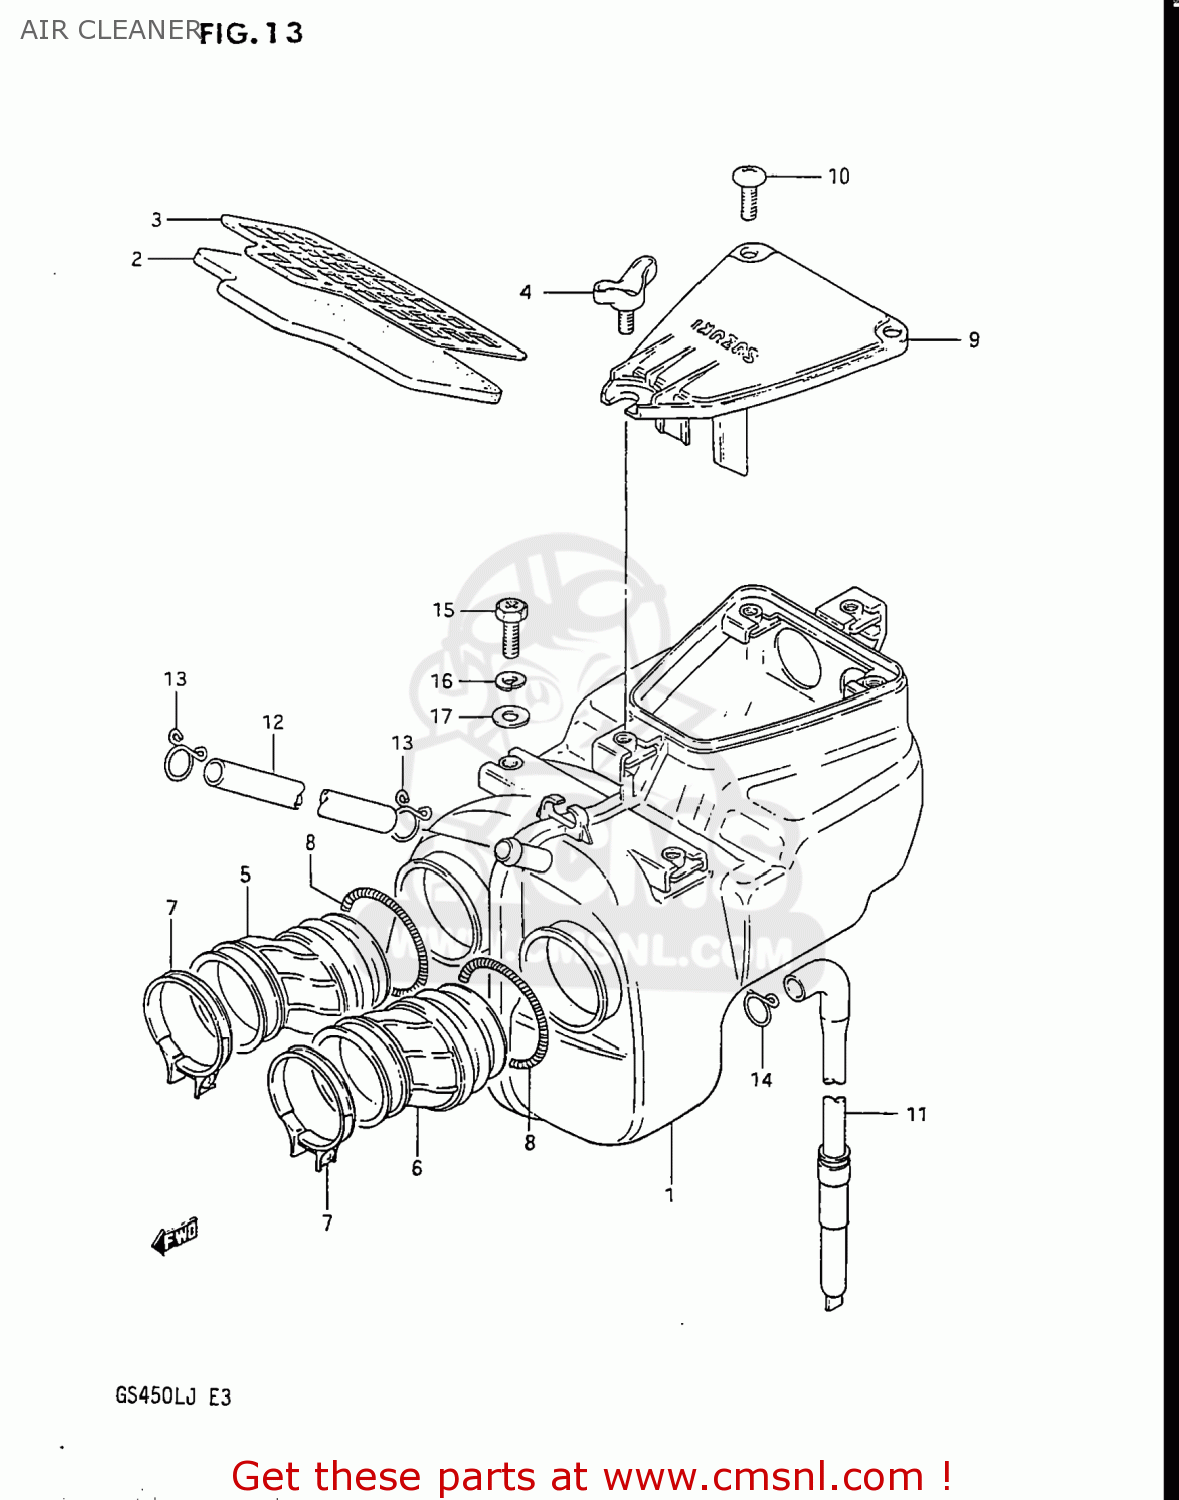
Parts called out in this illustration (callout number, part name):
1	CLEANER ASSEMBLY,AIR
2	FILTER
3	HOLDER,OUTER
4	BOLT, WING
5	TUBE,OUTLET,R
6	TUBE,OUTLET,L
7	CLAMP
8	CLAMP,CLEANER SIDE
9	CAP,AIR CLEANER
10	SCREW
11	DRAIN TUBE
12	TUBE,BREATHER
13	CLAMP
14	CLIP
15	SCREW(6X12)
16	WASHER,LOCK
17	WASHER
